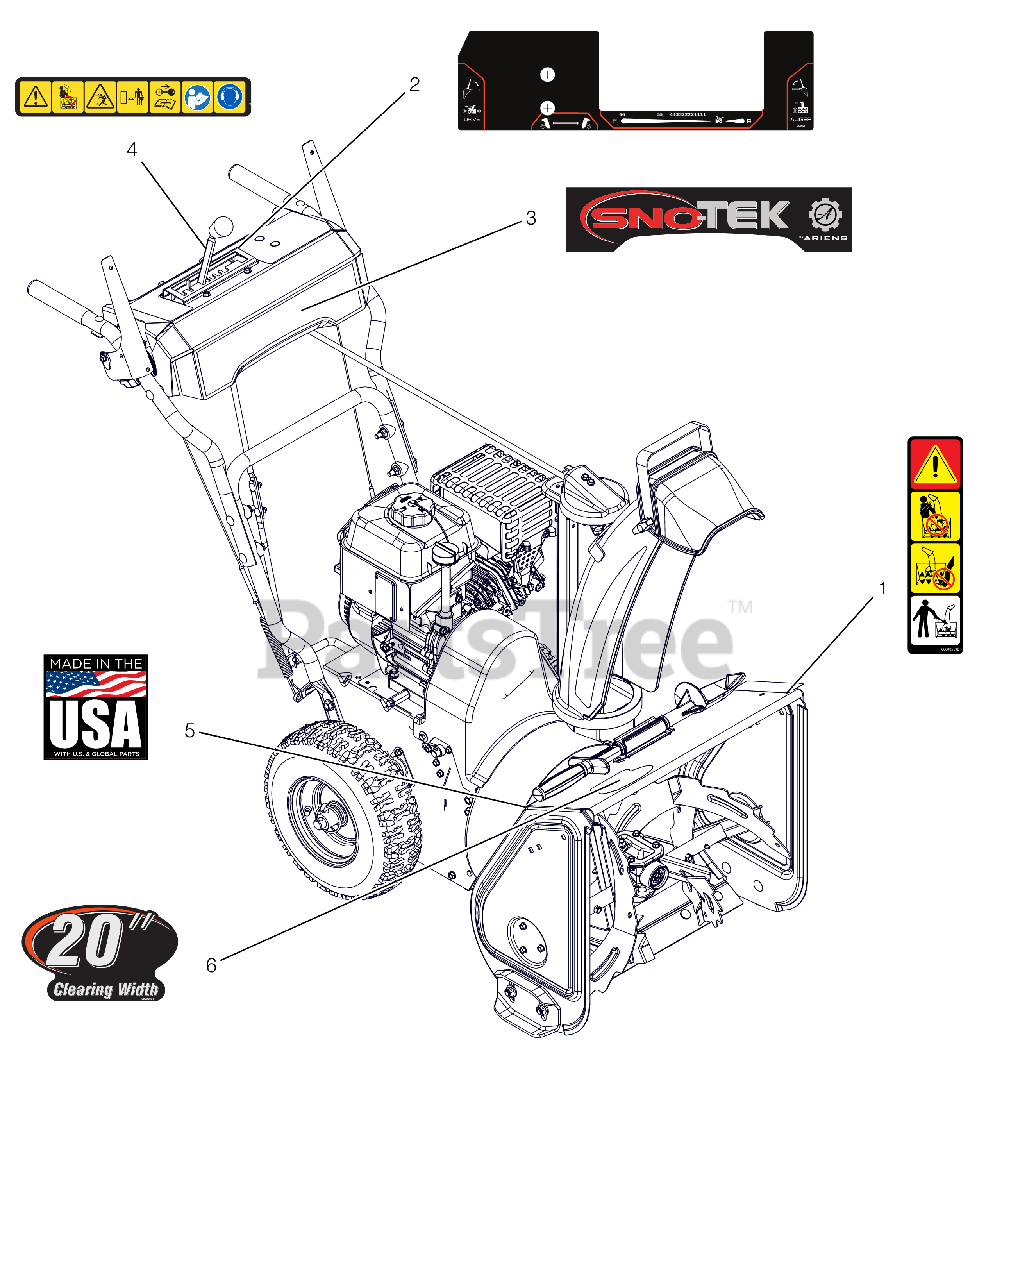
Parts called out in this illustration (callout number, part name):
1	DECAL, DANGER - ROTATING PARTS
2	DECAL,CONTROL-COMP MAN
3	DECAL, DASH, SNO-TEK
4	DECAL,DASH - SAFETY
5	DECAL, MADE IN USA
6	DECAL, HOUSING SNO-TEK 20
